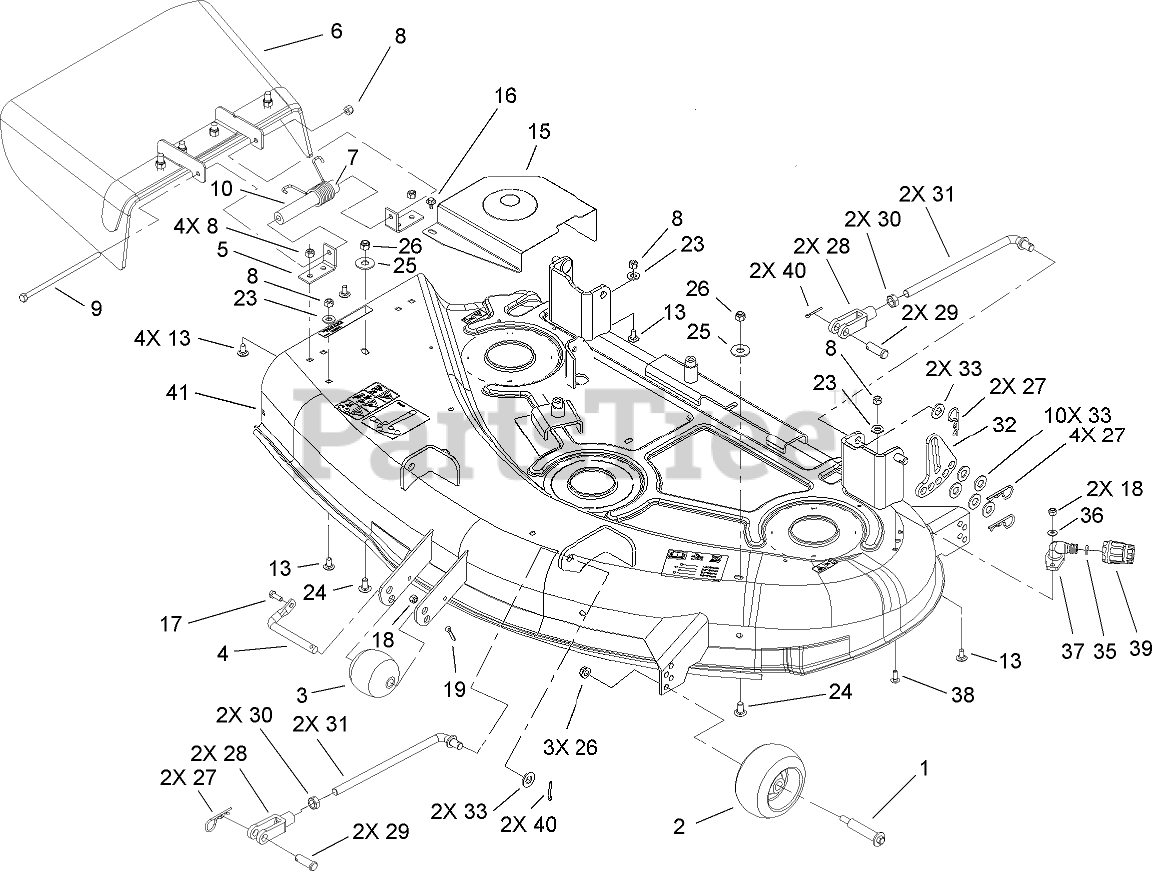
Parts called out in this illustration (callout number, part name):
1	BOLT-SHOULDER
2	ROLLER-SCALP, ANTI
3	ROLLER
4	Shaft-Roller
5	BRACKET-PIVOT, DEFLECTOR
6	DEFLECTOR ASM
7	SPRING-TORSION
8	NUT-LOCK, NI
9	BOLT-HH
10	SPACER-DEFLECTOR
13	SCREW-CARR
15	COVER-BELT, RH
16	SCREW-HHFTF
17	SCREW-HH
18	NUT-LOCK, NI
19	PIN-COTTER
23	WASHER-FLAT
24	SCREW-CARR
25	WASHER-FLAT
26	NUT-LOCK, NI
27	PIN-COTTER
28	CLEVIS
29	PIN-CLEVIS
30	NUT-JAM
31	ROD-TRUNION
32	LINK-HOC, ADJUSTING
33	WASHER-FLAT
35	O-RING
36	WASHER-FLAT
37	FITTING-WASHOUT
38	BOLT-CARR
39	CONNECTOR-HOSE
40	PIN-COTTER
41	44 INCH DECK ASM
